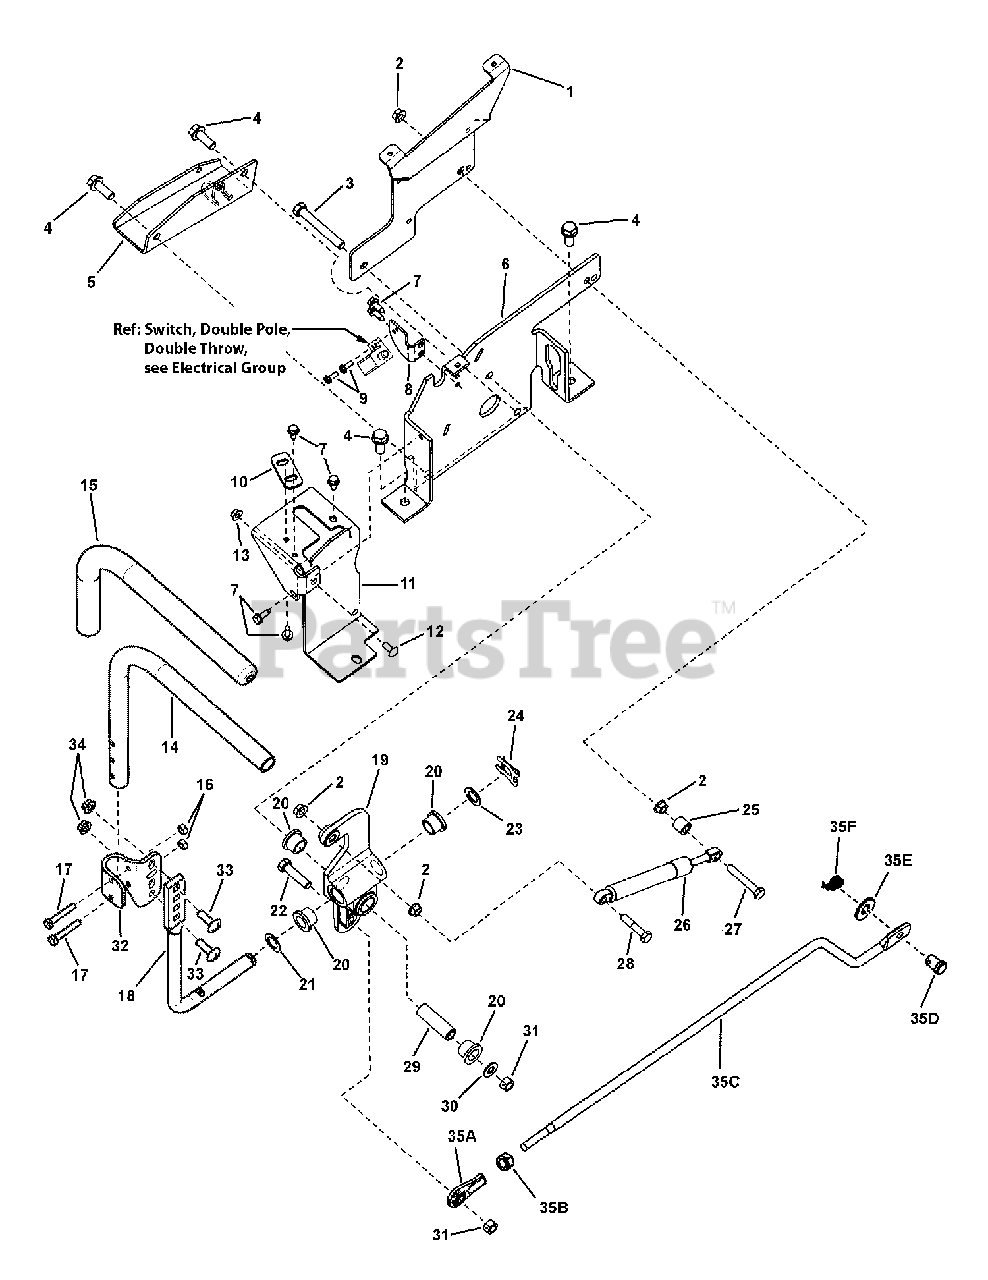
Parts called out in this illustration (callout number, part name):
1	BRACKET, Fender Support, RH
2	NUT, 5/16-18 Hex Flange Lock, GR 5, YZ
3	SCREW, 3/8-16 x 3-1/4" Hex Head Cap, GR 5, Black
4	SCREW, 3/8-16 x 1" Hex Washer Self-Tap
5	BRACKET, Motor Mount
6	BRACKET, Control, RH
7	SCREW, 1/4-20 x 3/4" Hex Washer Self-Tap, Black
8	BRACKET, Switch
9	SCREW, #10-24 x 1/2" Hex Washer Self-Tap (Torx)
10	PLATE, Fwd/Rev Adjust
11	BRACKET, Guide, Stick, Control, RH
12	BOLT, 1/4-20 x 5/8" Round Head Short Square Neck, GR 5, YZ
13	NUT, 1/4-20 Hex Flange Lock, Black
14	HANDLE, Adjustable
15	GRIP, Handle
16	NUT, 1/4-20 Hex Center Lock, GR 5 BZ
17	SCREW, 1/4-20 x 1-1/2" Hex Head Cap, GR 5, Black
18	ROD, Handle, Adjustable
19	ARM, Control, Die Cast, RH
20	BUSHING, Bronze, 5/8 x 5/8
21	WASHER, 5/8" Flat, YZ
22	SCREW, 3/8-16 x 1-1/2" Hex Head Cap, GR 5, YZ
23	WASHER, 5/8 ID. x 1" OD. x .065 Nylon
24	CLIP, Spring, 5/8 OD Shaft
25	SPACER, .625 OD x .380 ID x .564 L
26	DAMPENER, Control
27	SCREW, 5/16-18 x 2" Hex Head Cap, GR 5
28	SCREW, 5/16-18 x 1-1/2 Hex Head Cap, GR 5, YZ
29	SPACER, Sleeve, RZT
30	WASHER, 3/8" Flat (SAE) YZ
31	NUT, 3/8-16 Hex Center Lock, GR 5, YZ
32	BRACKET, Handle Adjustment
33	BOLT, 5/16-18 x 1" Round Head Square Neck, GR 5, YZ
34	NUT, 5/16-18 Hex Flange Two-Way Lk Ga
35A	ROD END (3/8-24 thread)
35B	NUT, 3/8-24 Hex, GR 5, YZ
35C	ROD, Link Forward/Reverse
35D	CLEVIS PIN, 7/16 X 1"
35E	WASHER, 7/16" Flat
35F	COTTER PIN, 1/2 Self, YZ
